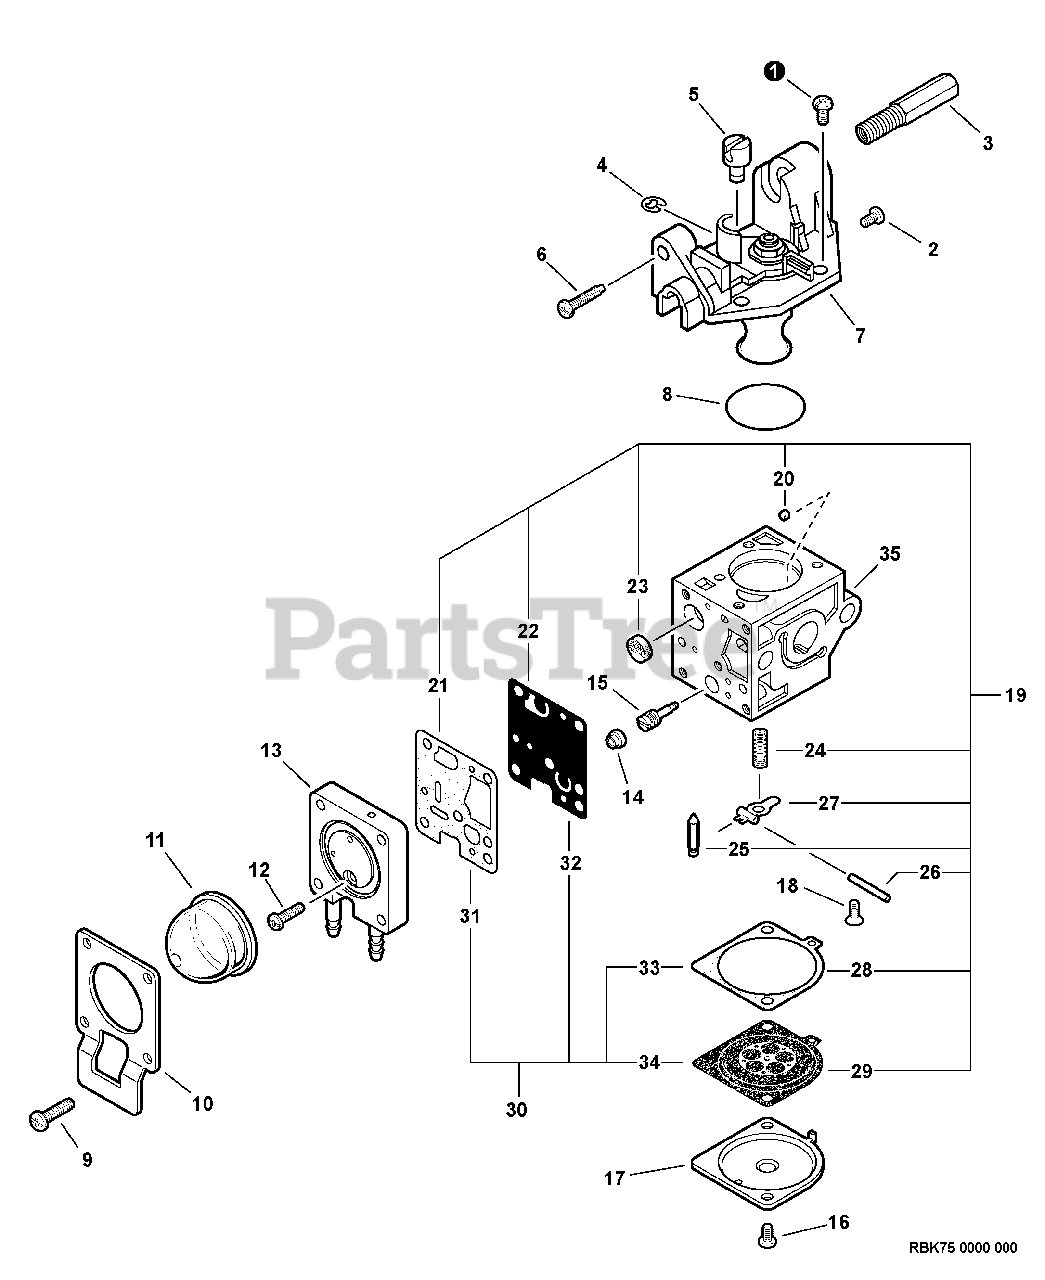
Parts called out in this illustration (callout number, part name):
3	ADJUSTER, THROTTLE CABLE
6	SCREW, IDLE ADJUST
7	VALVE ASSY, THROTTLE
9	SCREW
10	RETAINER, PURGE BULB
11	BULB, PURGE
13	BODY ASSY, PURGE
15	NEEDLE, HIGH SPEED
17	COVER, METERING DIAPHRAGM
19	REPAIR KIT
20	GUIDE, ROLLER
21	GASKET, PUMP
22	DIAPHRAGM, PUMP
23	STRAINER
24	SPRING, METERING LEVER
25	VALVE, INLET NEEDLE
26	PIN, METERING LEVER
27	LEVER, METERING
28	GASKET, DIAPHRAGM
29	DIAPHRAGM, METERING
30	GASKET / DIAPHRAGM KIT
31	GASKET, PUMP
32	DIAPHRAGM, PUMP
33	GASKET, DIAPHRAGM
34	DIAPHRAGM, METERING
35	BODY, CARBURETOR
